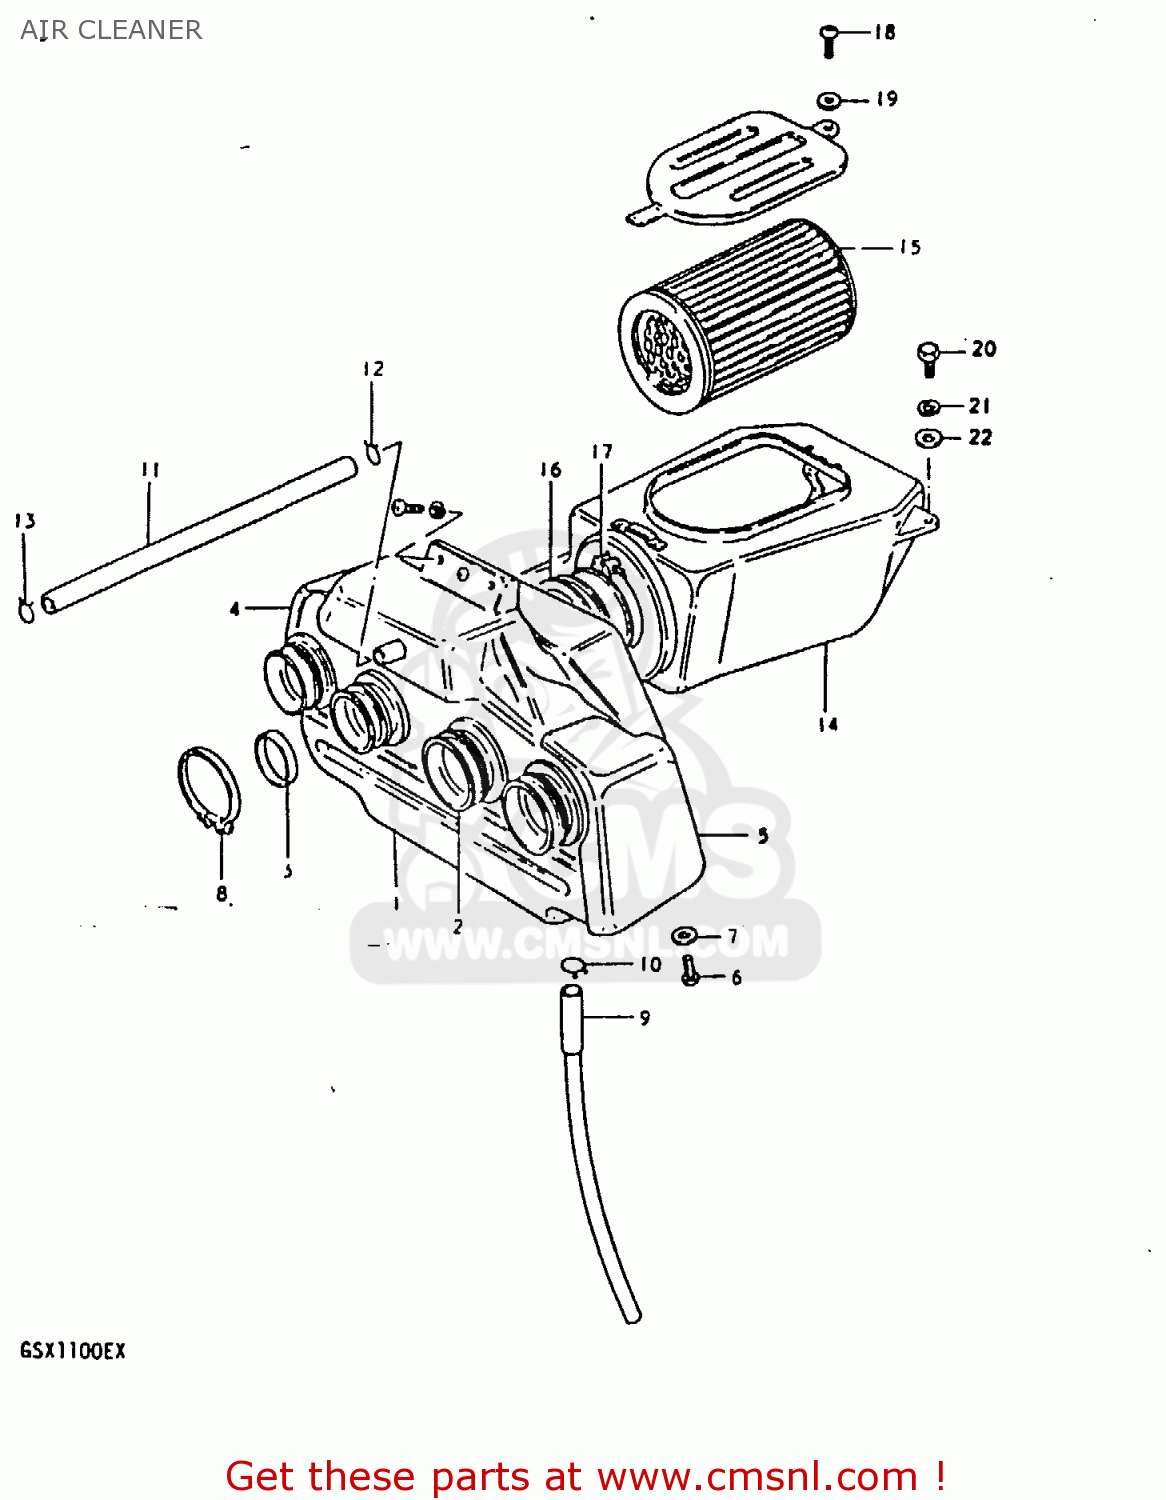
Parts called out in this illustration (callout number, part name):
1	CASE COMP,AIR CLEANER
2	TUBE,AIR CLEANER OUTLET
3	RING,CARBURETOR AIR IN
4	COVER,AIR CLEANER,RIGHT
5	COVER,AIR CLEANER,LEFT
6	SCREW
7	WASHER
8	CLAMP
9	DRAIN TUBE
10	CLIP
11	HOSE
12	CLIP,BREATHER HOSE
13	CLIP
14	CLEANER ASSEMBLY,AIR
15	FILTER,AIR CLEANER
16	JOINT,HOSE AIR CLEANER
17	CLAMP
18	SCREW
19	WASHER
20	BOLT
21	LOCK WASHER
22	WASHER
